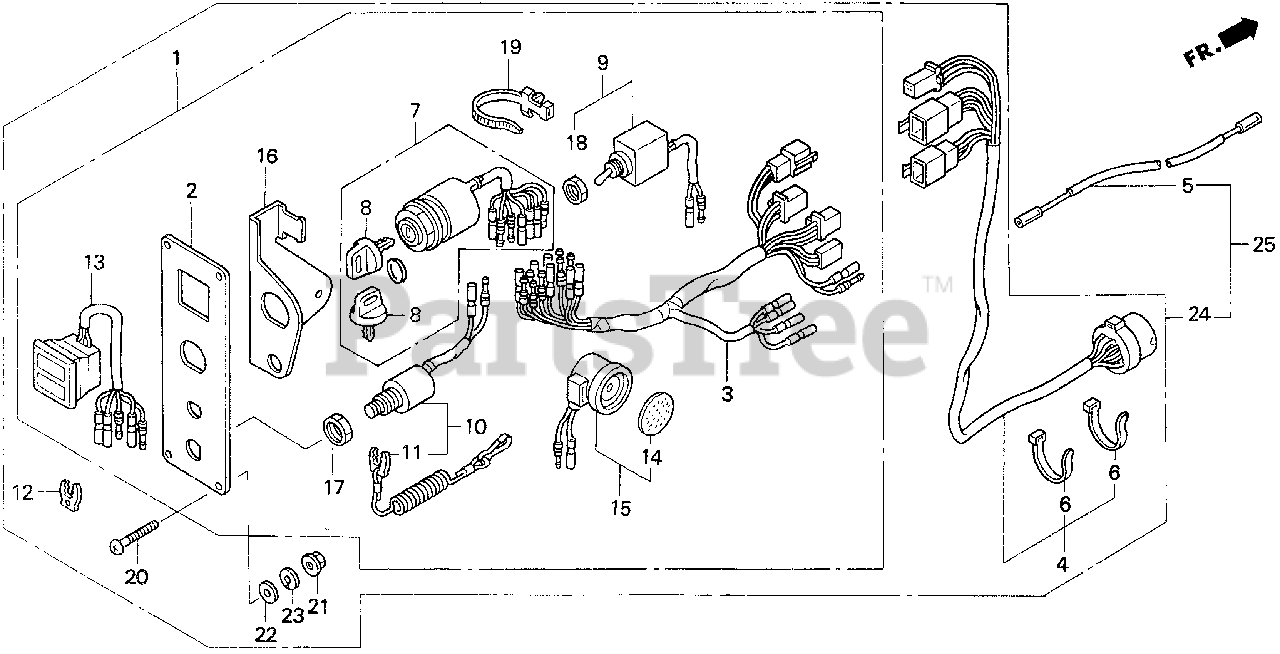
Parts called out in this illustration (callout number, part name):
1	PANEL ASSY., CONTROL
2	PANEL, CONTROL
3	HARNESS ASSY., SWITCH PANEL
4	CABLE (14WIRE) (16.5')
5	WIRE ASSY., GROUND
6	TIE, CABLE
7	SWITCH ASSY., COMBINATION
8	KEY ASSY., COMBINATION SWITCH
9	SWITCH ASSY., SOLENOID
10	SWITCH ASSY., EMERGENCY STOP
11	WIRE, EMERGENCY
12	CLIP, EMERGENCY LOCK
13	LAMP ASSY., INDICATOR
14	PLATE, TURN SIGNAL BUZZER
15	BUZZER, WARNING
16	BRACKET, BUZZER
17	NUT, HEX. (16MM)
18	NUT, HEX. (12MM)
19	BAND, WIRE HARNESS (WHITE)
20	SCREW, PAN (5X40)
21	NUT, FLANGE (5MM)
22	WASHER, PLAIN (5MM)
23	WASHER, SPRING (5MM)
24	PANEL KIT, SWITCH (SINGLE)
25	PANEL KIT, SWITCH (DUAL)
